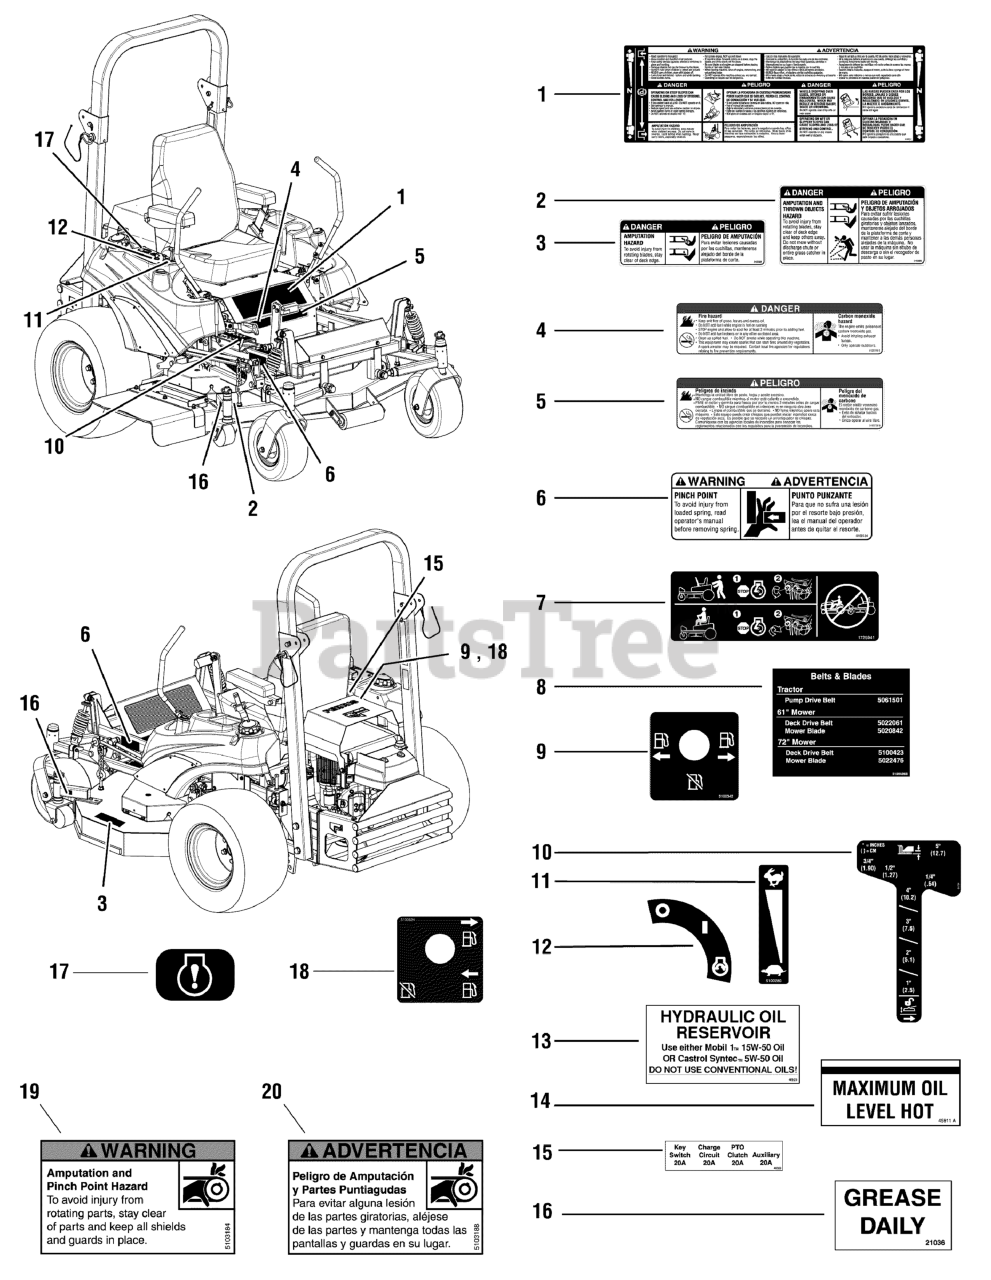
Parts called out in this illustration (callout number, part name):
1	DECAL, MAIN SAFETY
2	DECAL, DANGER, MOWER DISCHARGE,8.75X2.13
3	DECAL, DANGER, MOWER
4	DECAL, DANGER, FIRE
5	DECAL, DANGER, FIRE (SP)
6	DECAL, WARNING, PINCH POINT
7	DECAL, CZT HYRDO RELEASE
9	DECAL, FUEL VALVE
10	DECAL, DECK HEIGHT, IS1500ZX
11	DECAL, Throttle Control
12	DECAL, IGNITION CONTROL
13	DECAL, Oil Reservoir
14	DECAL, Max. Oil Level
15	DECAL, FUSE LOCATION, 20-20-20-20
16	* DECAL, GREASE DAILY
17	DECAL, INDICATOR LAMP
18	DECAL, FUEL VALVE, DFI
19	DECAL, WARNING, HAND IN BELT, ENG ONLY
20	DECAL, WARNING, HAND IN BELT, SPA ONLY
